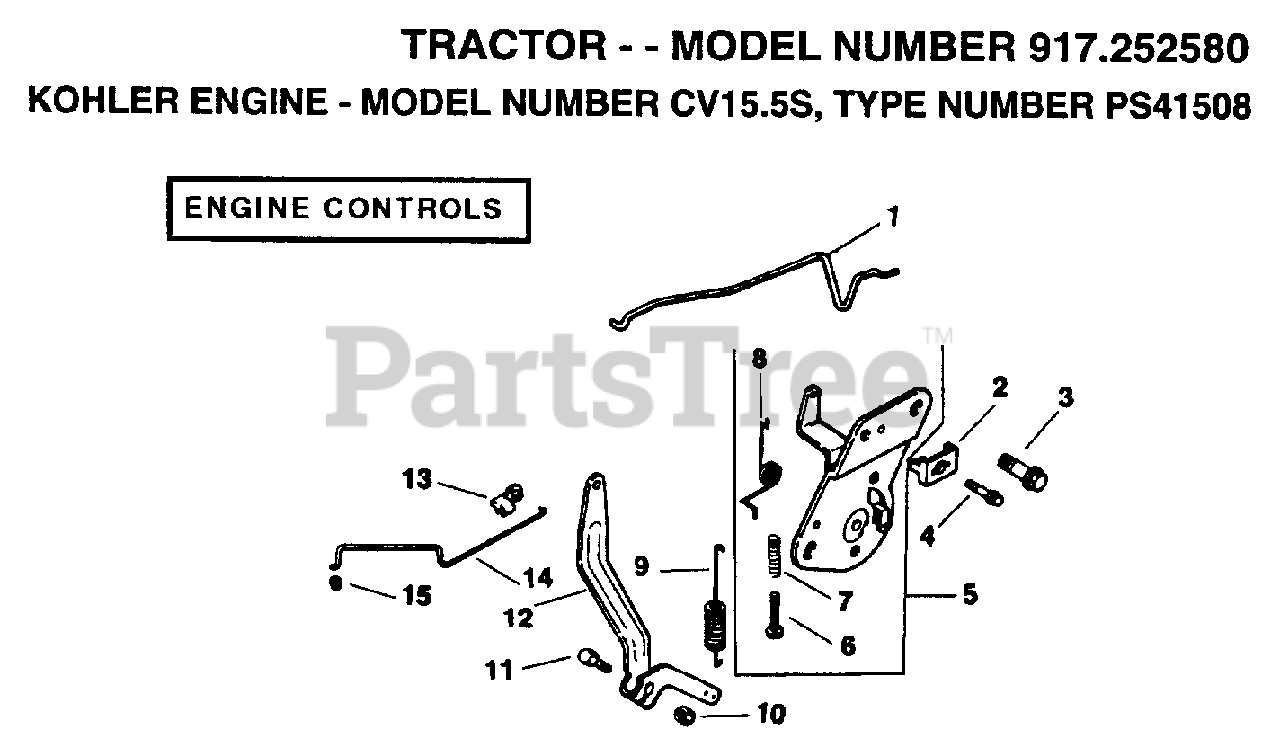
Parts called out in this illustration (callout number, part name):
1	LINKAGE, CHOKE
3	SCREW, HEX HEAD
4	SCREW, CABLE CLAMP
5	CONTROL, SPEED ASSEMBLY
7	SPRING, CHOKE ADJUST
8	SPRING, CHOKE RETURN
9	SPRING, GOVERNOR
10	NUT, GOVERNOR ARM
11	SCREW, GOVERNOR ARM
12	LEVER, GOVERNOR
14	LINKAGE, THROTTLE
